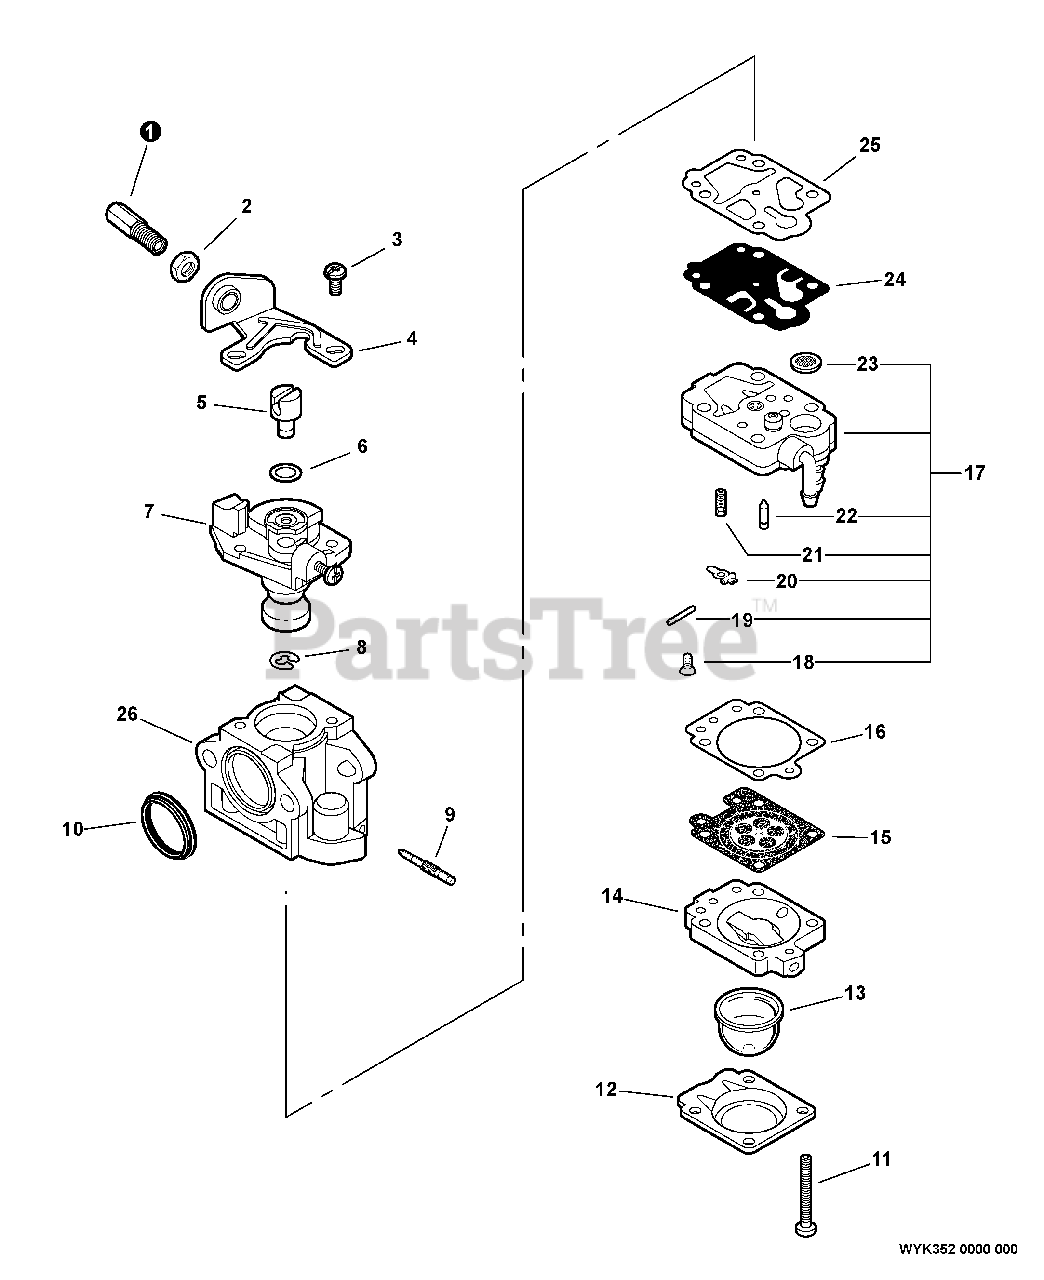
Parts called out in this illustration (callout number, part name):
1	NUT, CABLE ADJUST
4	BRACKET, THROTTLE CABLE
7	THROTTLE VALVE ASSY
8	RING, RETAINING
9	NEEDLE - HIGH SPEED
11	SCREW, PUMP COVER
12	RETAINER, PURGE BULB
13	BULB, PURGE
14	PURGE BASE ASSY
15	DIAPHRAGM, METERING
16	GASKET, METERING
17	PUMP BODY ASSY
18	SCREW, METERING LEVER PIN
19	PIN, METERING LEVER
20	LEVER, METERING
21	SPRING, METERING LEVER
22	VALVE, INLET NEEDLE
23	STRAINER
24	DIAPHRAGM, PUMP
25	GASKET, PUMP
26	BODY, CARBURETOR
